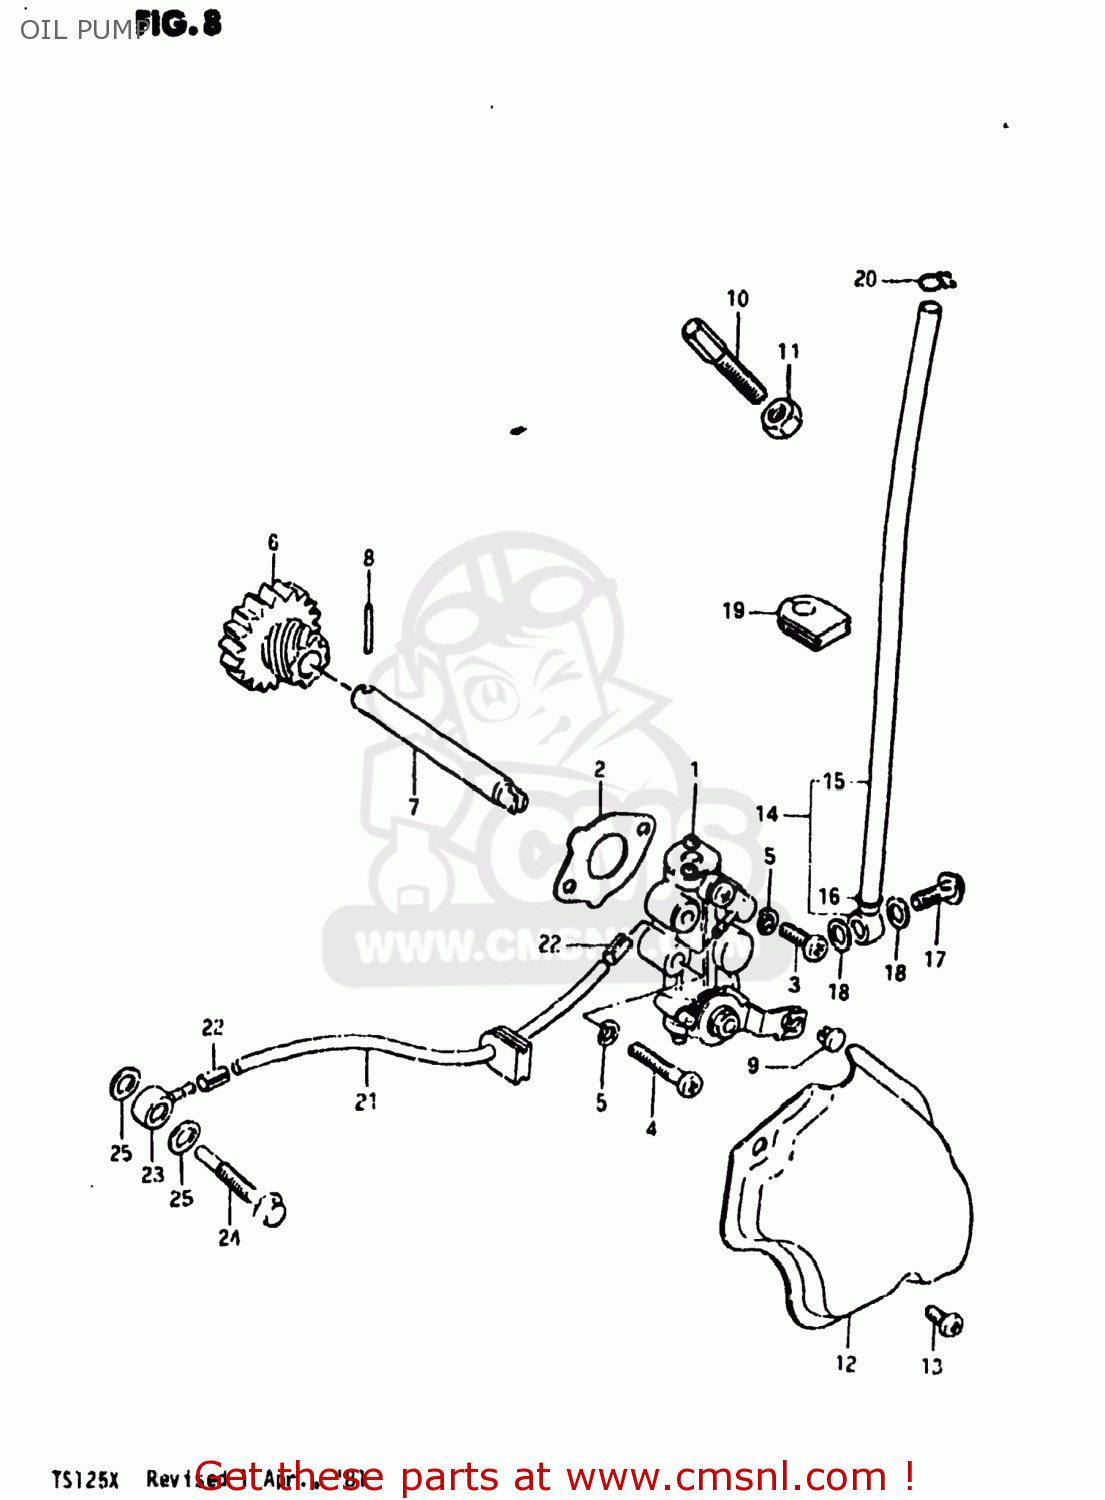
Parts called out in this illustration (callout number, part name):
1	PUMP ASSY,OIL
2	GASKET,OIL PUMP (NAS)
3	SCREW
4	SCREW
5	LOCK WASHER
6	GEAR,OIL PUMP DRIVE
7	SHAFT,OIL PUMP DRIVE
8	PIN(2.5X19.8)
9	TERMINAL,CABLE
10	BOLT
11	NUT
12	CAP,OIL PUMP INSPECTION
13	SCREW
14	HOSE,OIL NO.1
15	HOSE
16	CLIP
17	UNION BOLT
18	GASKET(6.2X11X1).2 (NAS)
19	GROMMET
20	CLIP
21	HOSE,OIL NO.2
22	CLIP
23	UNION
24	UNION
25	GASKET(6.2X11X1).2 (NAS)
